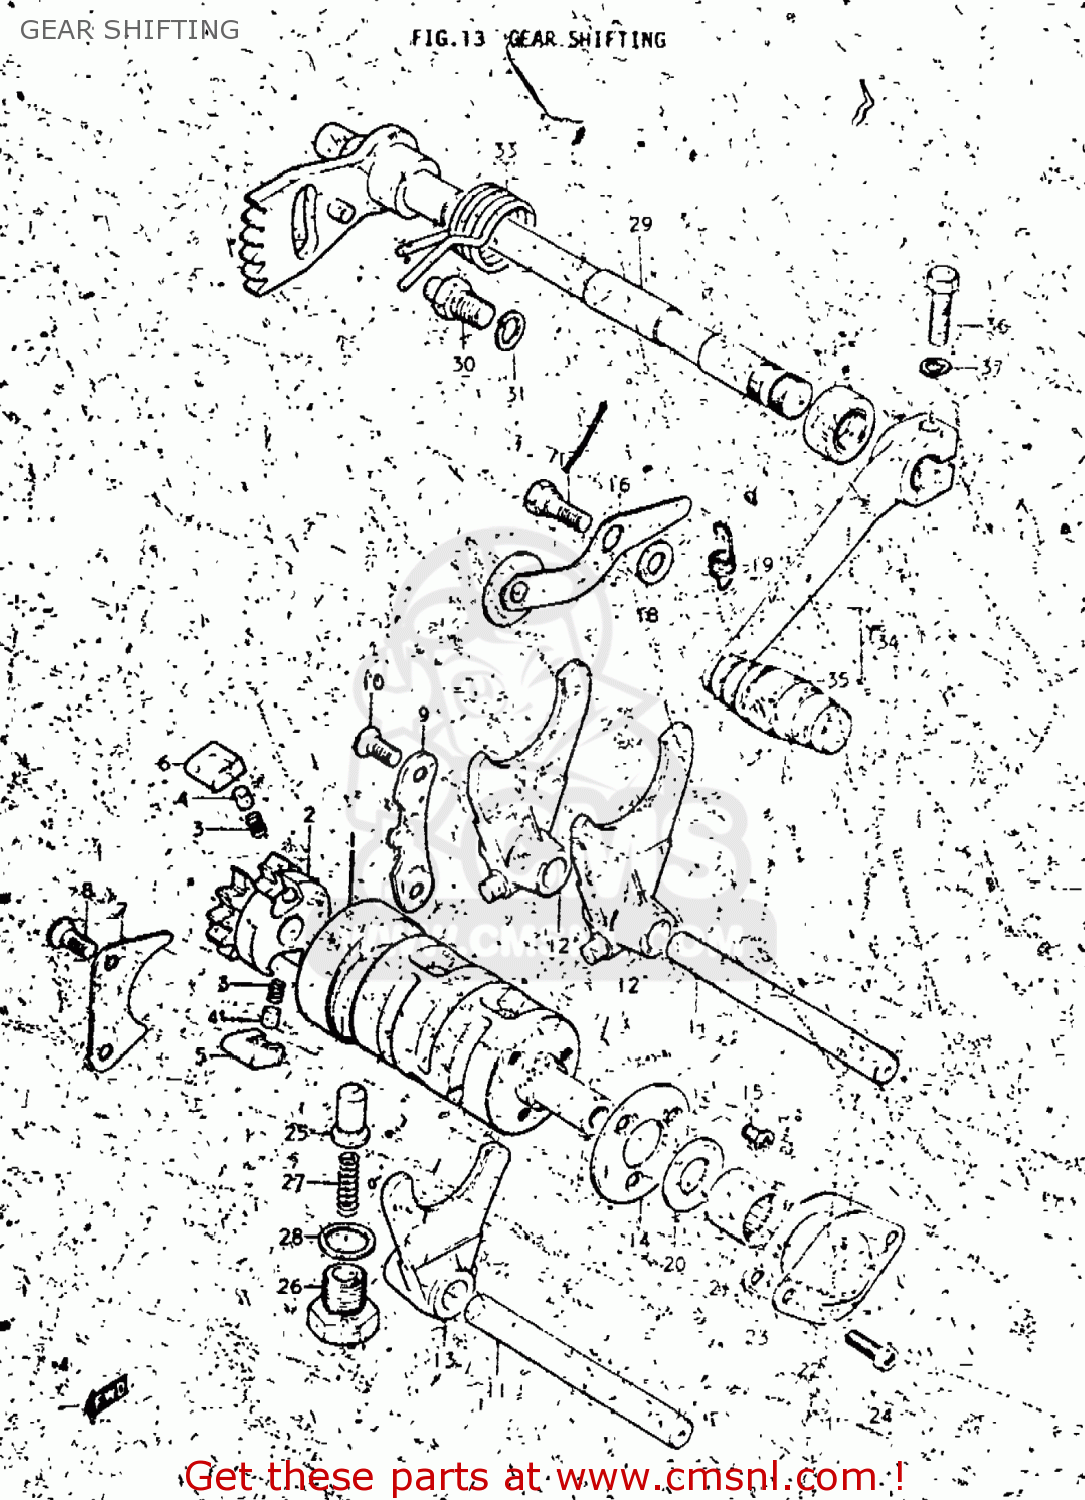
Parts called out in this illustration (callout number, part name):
1	CAM,GEAR SHIFT
2	RETAINER,GEAR SHIFT CAM
3	SPRING
4	PIN(5X8)
5	PAWL,GEAR SHIFT NO.1
6	PAWL,GEAR SHIFT NO.2
7	LIFTER,GEAR SHIFT PAWL
8	SCREW
9	GUIDE,GEAR SHIFTING CABLE
10	SCREW
11	SHAFT,GEAR SHIFT FORK
12	FORK,GEAR SHIFT NO.1
13	FORK,GEAR SHIFT NO.3
14	PLATE,GEAR SHIFT CAM
15	SCREW
16	STOPPER,GEAR SHIFTING
17	BOLT(6X16.1)
18	WASHER
19	SPRING
20	WASHER
21	ROLLER BEARING (12X18X1
22	CAP,CAM PIVOT
23	GASKET (MCA)
24	Screw
25	STOPPER,GEAR SHIFTING
26	HOLDER,GEAR SHIFT CAM STOP SPR
27	SPRING
28	GASKET(14X19.2X2) (NAS)
29	SHAFT,GEAR SHIFT
30	STOPPER,GEAR SHIFT CAM
31	LOCK WASHER
32	OIL SEAL
33	SPRING
34	LEVER ASSEMBLY,GEAR SHIFTING
35	RUBBER,GEAR SHIFT PEDAL
36	BOLT
37	LOCK WASHER
